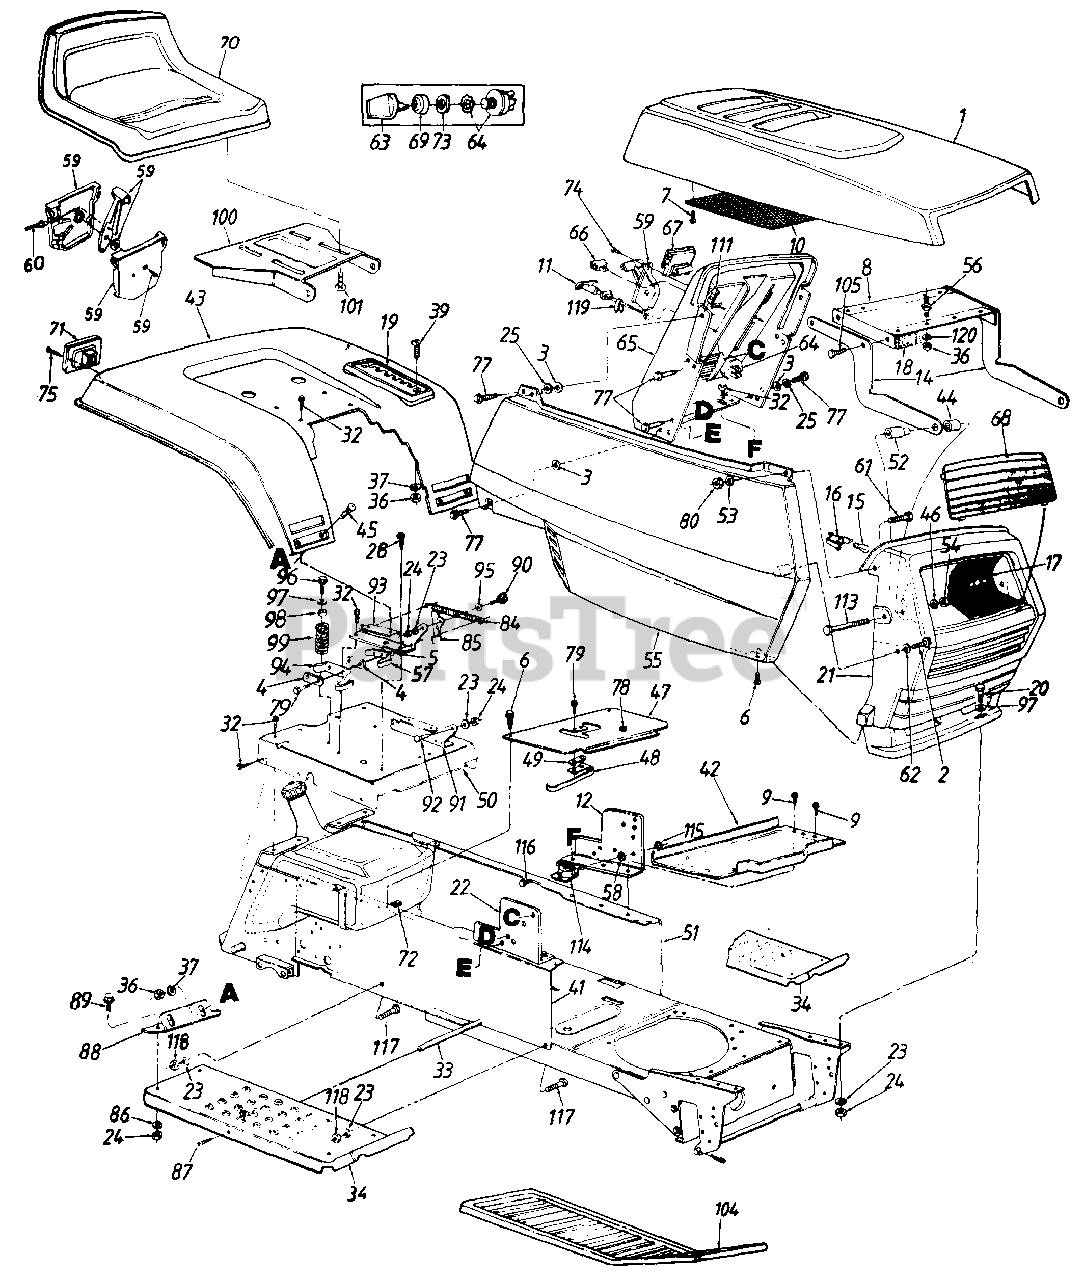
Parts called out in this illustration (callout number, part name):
3	Bolt Retainer 1/4" I.D.
4	Insulator Plate
5	Insulator Boss Plate
6	Truss Mach. B-Tap Scr. #10 x .5" Lg.
7	Hex Wash Hd. AB-Tap Scr. #8 x .5" Lg.
8	Hood Plate
9	Hex AB-Tap Scr. 1/4 x .62" Lg.
11	Choke Control
12	Dash Support Brkt. - L.H.
14	Hood Hinge
15	Lamp
16	Twist Lock - Lamp Socket
17	Reflector - Headlight
19	Speed Control Index Brkt.
20	Hex Bolt 5/16-18 x .75" Lg.
21	Grille
22	Dash Support Bracket - R.H.
23	L-Wash. 5/16" I.D.
24	Hex Nut 5/16-18 Thd.
25	Fl-Wash. 1/4" I.D. x .93" O.D.
32	Hex Wash. Hd. AB-Tap Scr. 5/16 x .75" Lg.
33	Running Board Rod
37	L-Wash. 1/4" I.D.
39	Truss Mach. Scr. 1/4-20 x .62"
41	R.H. Side Frame
42	Support Brkt.
45	Carriage Bolt 1/4-20 x .50" Lg.
46	Fl-Wash. .328" I.D. x .68" O.D.
47	Transmission Panel
48	Reverse Safety Switch
49	Insulator Nut Plate
53	Fl-Wash. .281" I.D. x .5" O.D.
54	Hex Cent. L-Nut 5/16-18 Thd.
55	Side Cover Ass'y. - R.H.
56	Double Ended Stud 1/4-20 Thd.
57	Safety Switch (Seat)
58	Ext. L-Wash. 1/4" I.D.
59	Throttle Control Box Ass'y.
60	Throttle Control Wire 35" Lg.
61	Hex Bolt 1/4-20 x .62" Lg.
62	Fl-Wash. .281" I.D. x .73" O.D.
64	Ignition Switch
65	Dash Panel
66	Light Switch
67	Ammeter
68	Lens
69	Ignition Switch Cap
71	Taillight Ass'y.
72	Speed Nut #10Z
73	Ignition Switch Nut
74	Truss Mach. AB-Tap Scr. #10 x .5" Lg.
75	Truss Hd. AB-Tap Scr. #6 x .62" Lg.
77	Hex Wash. Hd. Tap Scr. 1/4 x .75" Lg.
78	Snap Bushing
79	Hex Wash. Hd. AB-Tap Scr. #8 x .50" Lg.
80	Hex L-Nut 1/4-20 Thd.
84	Ext. Spring 5.31" Lg.
85	Seat Lift Brkt.
86	Bell-Wash. .345" I.D. x .88" O.D.
87	Rib Neck Bolt 5/16-18 x .75"
90	Shld. Bolt .437" Dia. x .268"
95	Spr.-Wash. .445" I.D.
96	Hex Wash. Hd. Tap Scr. 5/16-18 x 1" Lg.
97	Fl-Wash. .344" I.D. x 1" O.D.
99	Compression Spring
100	Seat Pivot Bracket
101	Hex Tap Scr. 3/8-16 x .75"
105	Hex Tap Scr. 1/4-20 x .5" Lg.
111	Speed Nut 1/4-20 Thd.
113	Hex Bolt 5/16-18 x 2.75"
114	Solenoid
115	Hex Sems Nut 1/4-20 Thd.
116	Hex Bolt 1/4-20 x .5" Lg.
117	Rib Neck Bolt 5/16-24 x .75" Lg.
118	Hex Nut 5/16-24 Thd.
119	Retainer Clip
120	Bell-Wash. .265" I.D. x .75" O.D.
